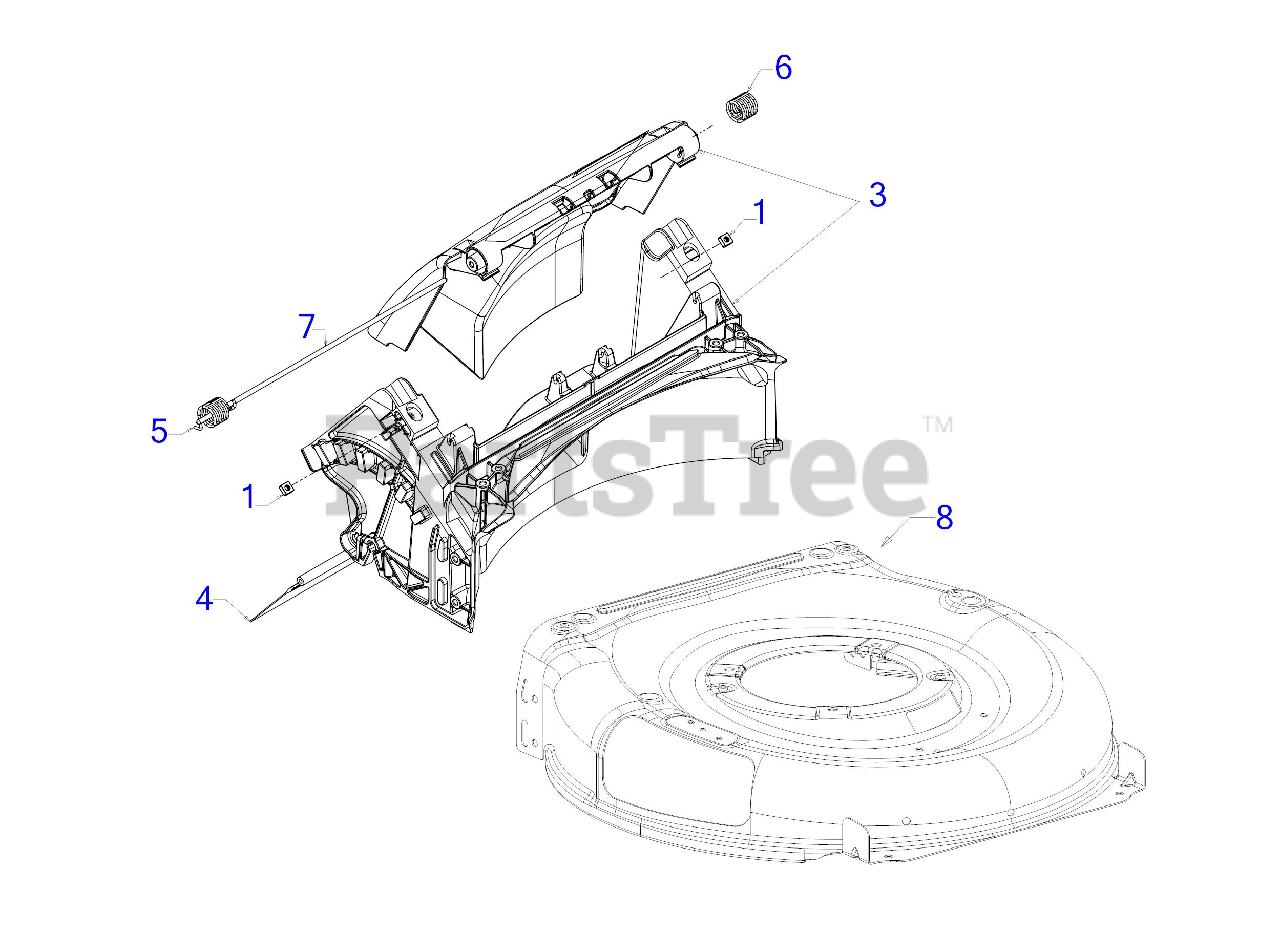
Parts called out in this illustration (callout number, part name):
1	SQUARE NUT 1/4-20
3	REAR BAG DOOR ASSEMBLY
4	TRAILSHIELD
5	TORSION SPRING (RH)
6	TORSION SPRING (LH)
7	REAR DOOR PIVOT ROD
